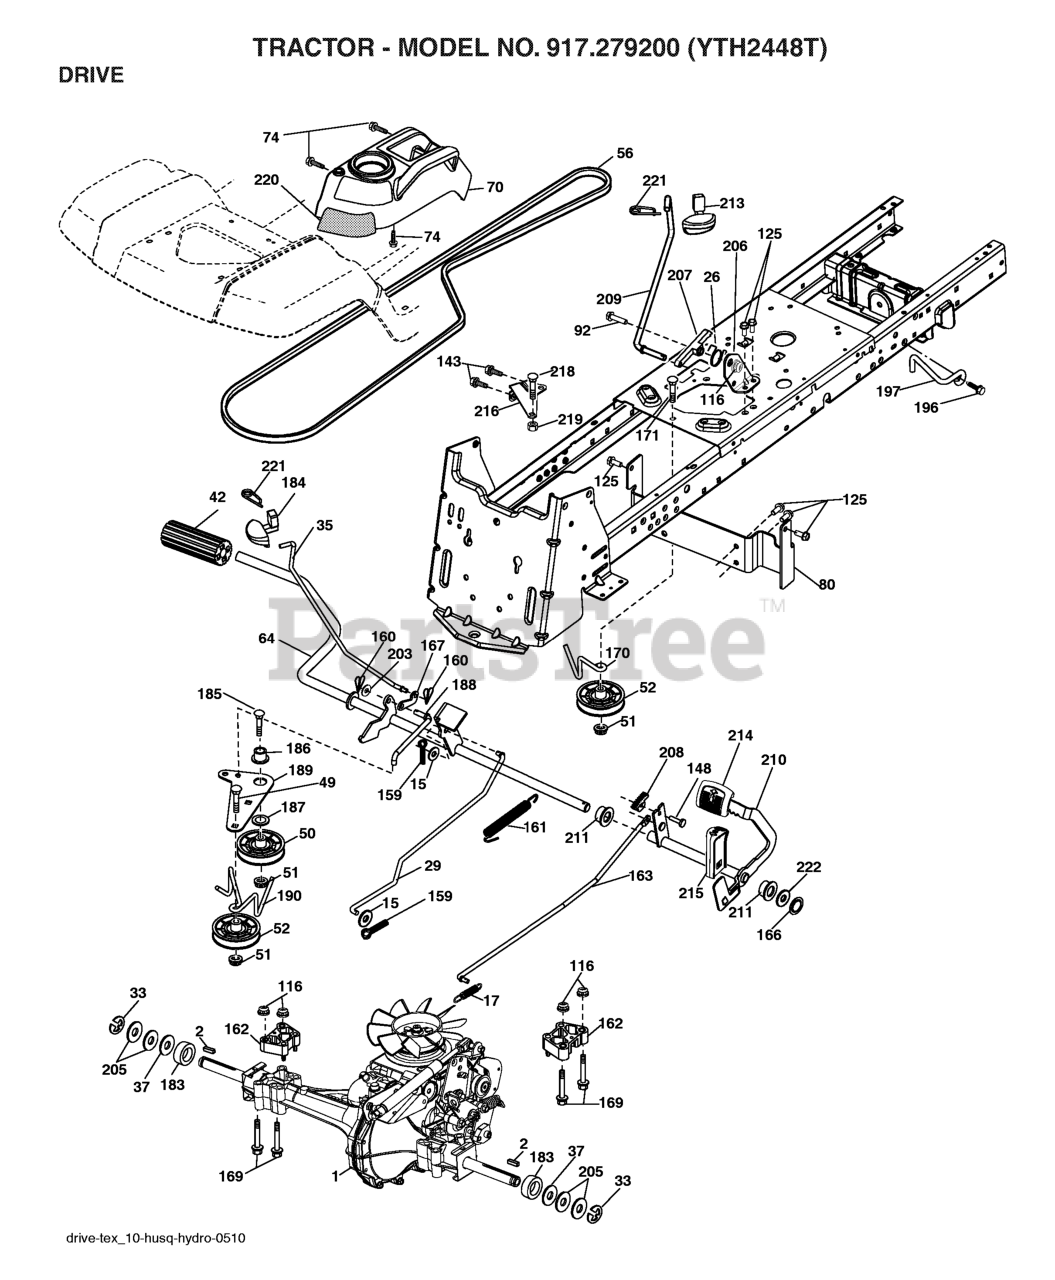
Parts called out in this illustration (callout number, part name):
2	SQUARE KEY
15	WASHER
17	SPRING.BRAKE.HG3000/3500
26	SPRING.RETURN.CRUISE
29	ROD.BRAKE.0610.PEDAL.CONTROL
35	ROD.BRAKE.PARKING.GT.H
42	PEDAL COVER T
50	IDLER.FLAT.910.OFFSET
51	NUT LOCK FLG 3/8-16 UNC
52	IDLER.V-GROOVE.910.OFFSET
64	SHAFT.ASM.PEDAL.BRK.CNTR
70	RP CONSOLE.ASM.PCH.W/TB
74	SCREW.HI-LO.CONSOLE
80	BRKT.STRP.TRQ.LT.HYD.C
92	BOLT
116	NUT LOCK HEX FLANGE 5/16-18
125	SCREW
143	Screw 5/16-18 x 1/2 Hex, Self Tapping 5/16-18 x 1/2
148	SCREW, 3/8-16X3/4
159	COTTER PIN
160	RETAINER CLIP
161	SPRING.RETURN.CLUTCH.2006
162	SPACER.TRANSAXLE.18&22
163	ROD.PEDAL.CONTROL.0510
166	NUT.PUSH.625.2006
167	LATCH.BRAKE.SPRING
169	BOLT.HEX.FLNG.5/16-18X3.75
170	KEEPER.V-IDLER.CENTER.
183	SPACER AXLE
184	HANDLE.PARKG.BRK.HUSQ X667
186	SPACER.RETAINER
187	WASHER 12/32X2X10GA
188	RP.LINK.CLUTCH.GROUND.DRIVE
189	BELLCRANK.GROUND.DRIVE.TEX.
190	KEEPER.BELLCRANK.DRIVE
196	SCREW 3/8-16X1
197	BRKT.ANIT-ROTATION.CLUTCH
203	WASHER
206	BRKT.MOUNT.LATCH.CRUIS
207	LATCH.CONTROL.CRUISE
208	GEAR.SECTOR.CONTROL.CR
209	ROD.CONTROL.CRUISE.GT.
210	ROCKER.ASM.PEDAL.CONTR
211	BEARING.NYLON
213	KNOB.CONTROL.CRUSIE.HU
214	PEDAL.FORWARD.TEX.GT.4
215	PEDAL.REVERSE.TEX.GT.4
216	BRACKET.PULLEY.IDLER.W/TEX
218	BOLT.5/16-18X1-1/4 FULL.THREAD
219	SPACER.FENDER
220	REFLECTOR.RH.TEX GT
221	RETAINER.SPRING.CLIP.H
